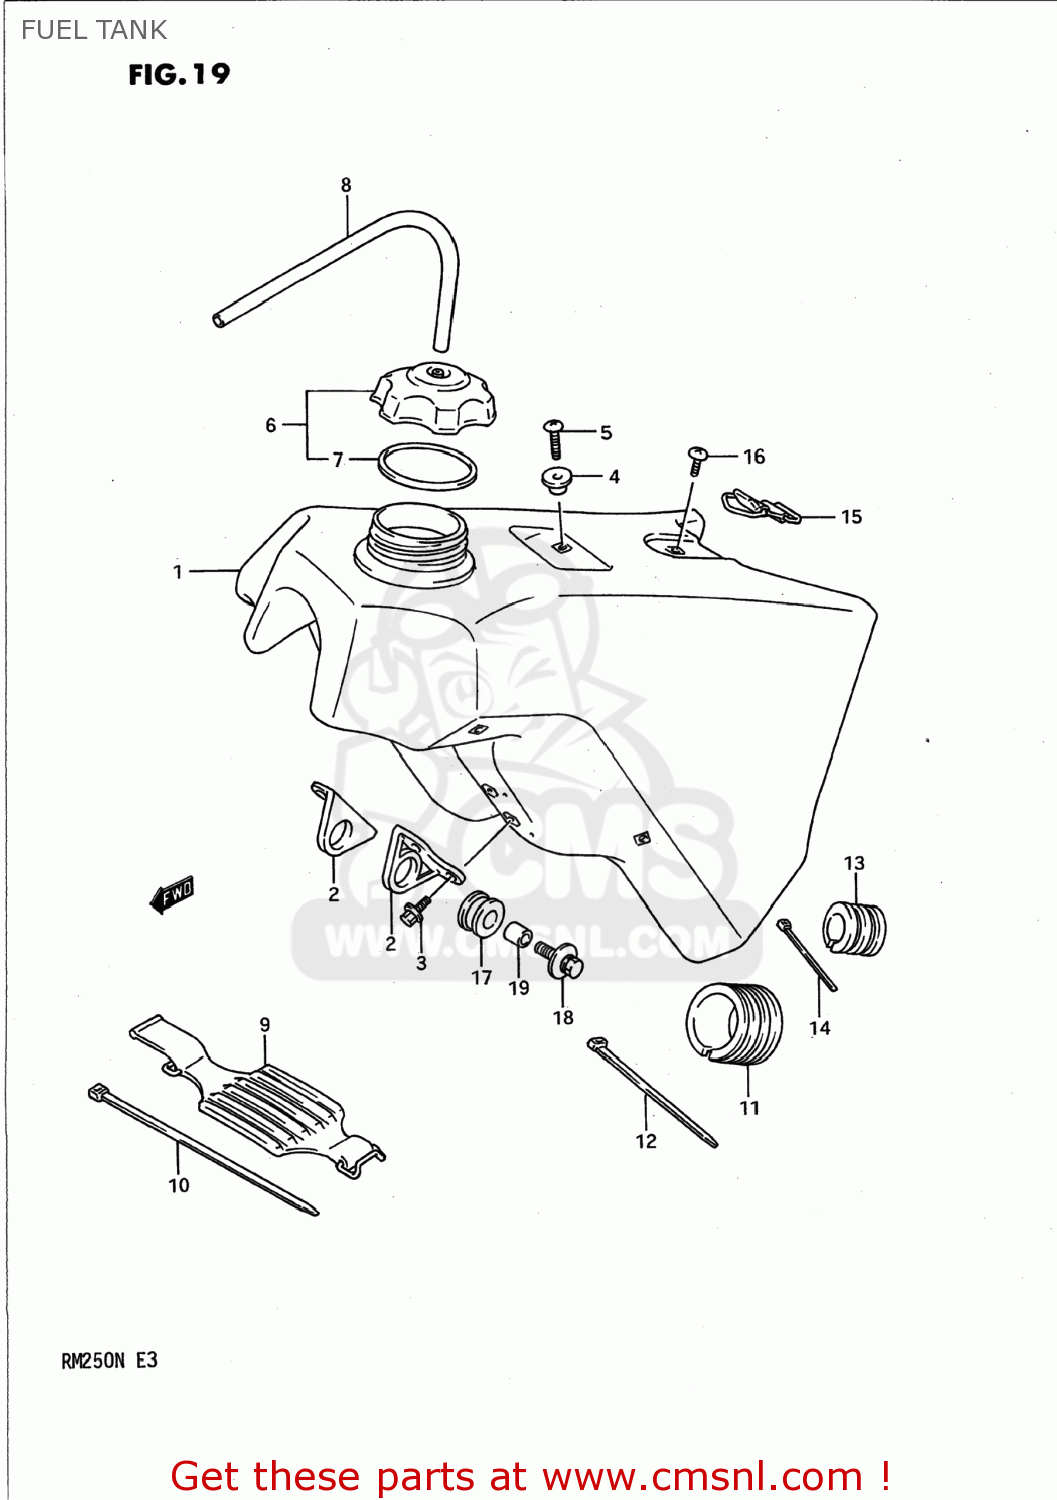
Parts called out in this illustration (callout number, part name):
1	TANK SET,FUEL
2	BRACKET,FUEL TANK FR
3	BOLT
4	HOOK,SEAT,FRONT
5	SCREW
6	CAP SET,FUEL TANK
7	GASKET,CAP (NAS)
8	HOSE(5X9X600)
9	CUSHION,FUEL TANK NO.1
10	CLAMP
11	CUSHION,FUEL TANK NO.2
12	CLAMP(L:300)
13	CUSHION,FUEL TANK NO.1
14	CLAMP(L:145)
15	BAND,FUEL TANK RR
16	SCREW
17	CUSHION
18	BOLT(8X30)
19	SPACER (8.8X12X13.5)
